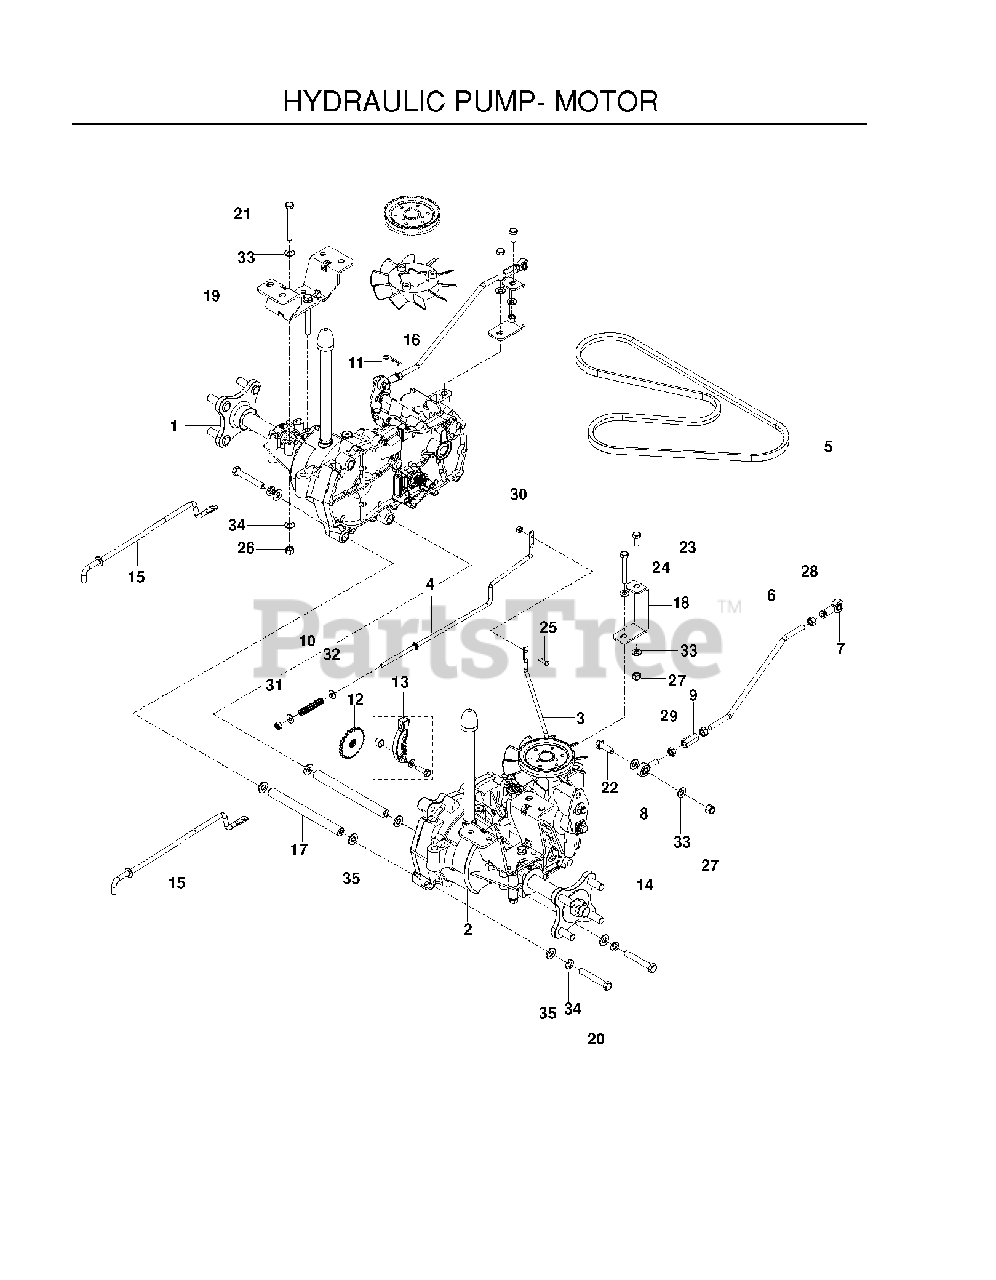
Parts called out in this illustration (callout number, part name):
1	HG_EZT, LT
2	HG_EZT, RT
3	LINKAGE.BRAKE.LT
4	LINKAGE, BRAKE RT
5	BELT, HYDRO PUMP
6	ROD, MOTION CONTROL
7	RH ROD END
8	ROD.END.LH
9	ROD END COUPLER
10	SPRING
11	HAIRPIN #2
12	HG_DISC COG BRAKE
13	HG_KIT BRAKE ARM (EZT)
14	HG_KIT, HYDRO-GEAR HUB
15	LINKAGE, BYPASS, EZT
16	HG_HYDRO FAN
17	SPACER TUBE, EZT
18	SUPPORT.FRONT.TRANS.BLACK.
19	EZT MOUNT, REAR, BLACK
20	HCS 3/8C X 2 1/2
21	HCS 5/16C X 2-3/4
22	HCS 5/16C X 1
23	HCS 5/16C X 3/4
24	CAPSCREW
25	SCR #10-24 X 3/4
26	NUT 5/16 NYLOC
27	5/16-18 THIN PROF NY
28	NUT 5/16F
29	NUT 5/16F LEFTHAND
30	NUT 10-24 NYLOC
31	NUT 1/4-20 NYLOC
32	WASHER 1/4 SAE
33	FLAT WASHER 5/16 SAE
34	SLW 3/8 STD
35	WASHER 3/8 SAE FLAT
